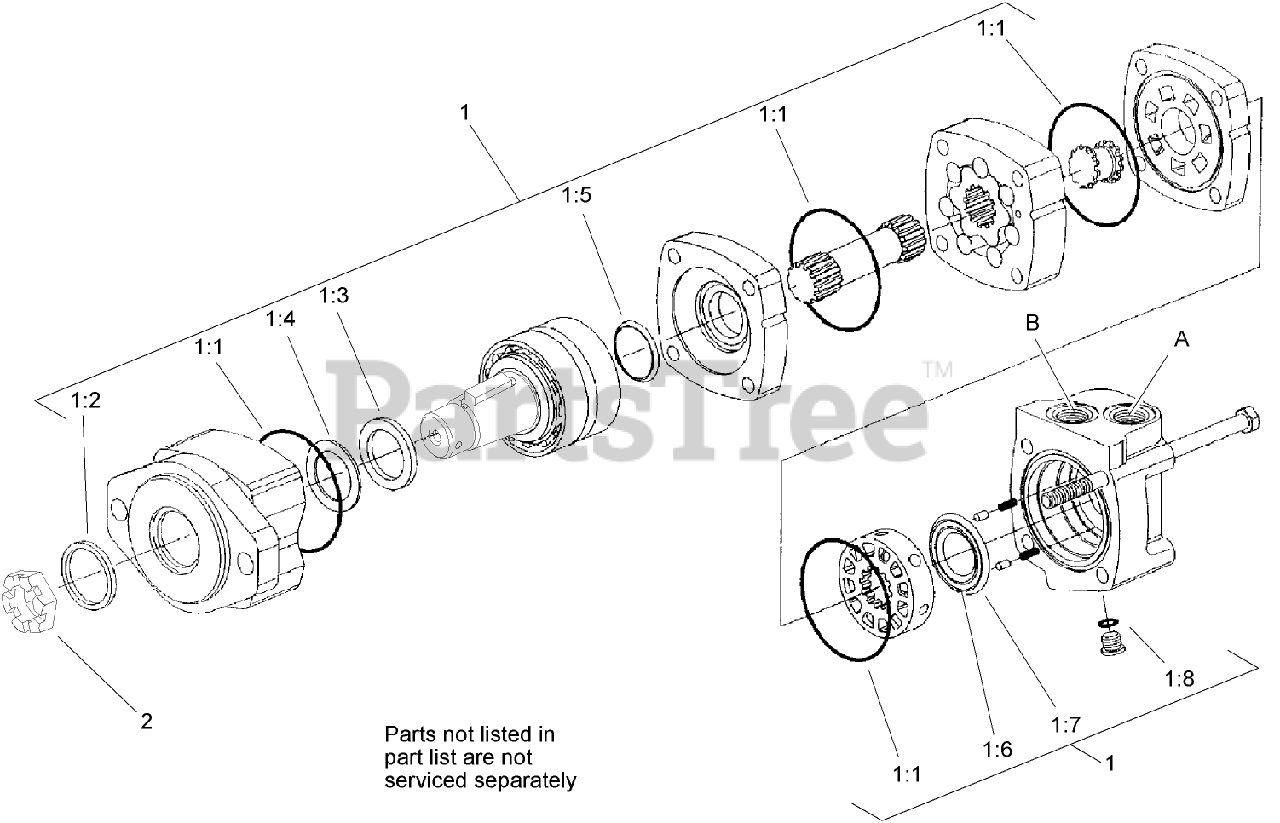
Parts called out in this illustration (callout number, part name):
1	SEAL KIT
1:1	O-Ring (Not serviced separately)
1:2	Seal-Exclusion, Shaft (Not serviced separately)
1:3	Seal-Shaft (Not serviced separately)
1:4	Ring-Back-Up (Not serviced separately)
1:5	Seal-Face, Shaft (Not serviced separately)
1:6	Seal-Face, Inner (Not serviced separately)
1:7	Seal-Face, Outer (Not serviced separately)
1:8	O-Ring (Not serviced separately)
